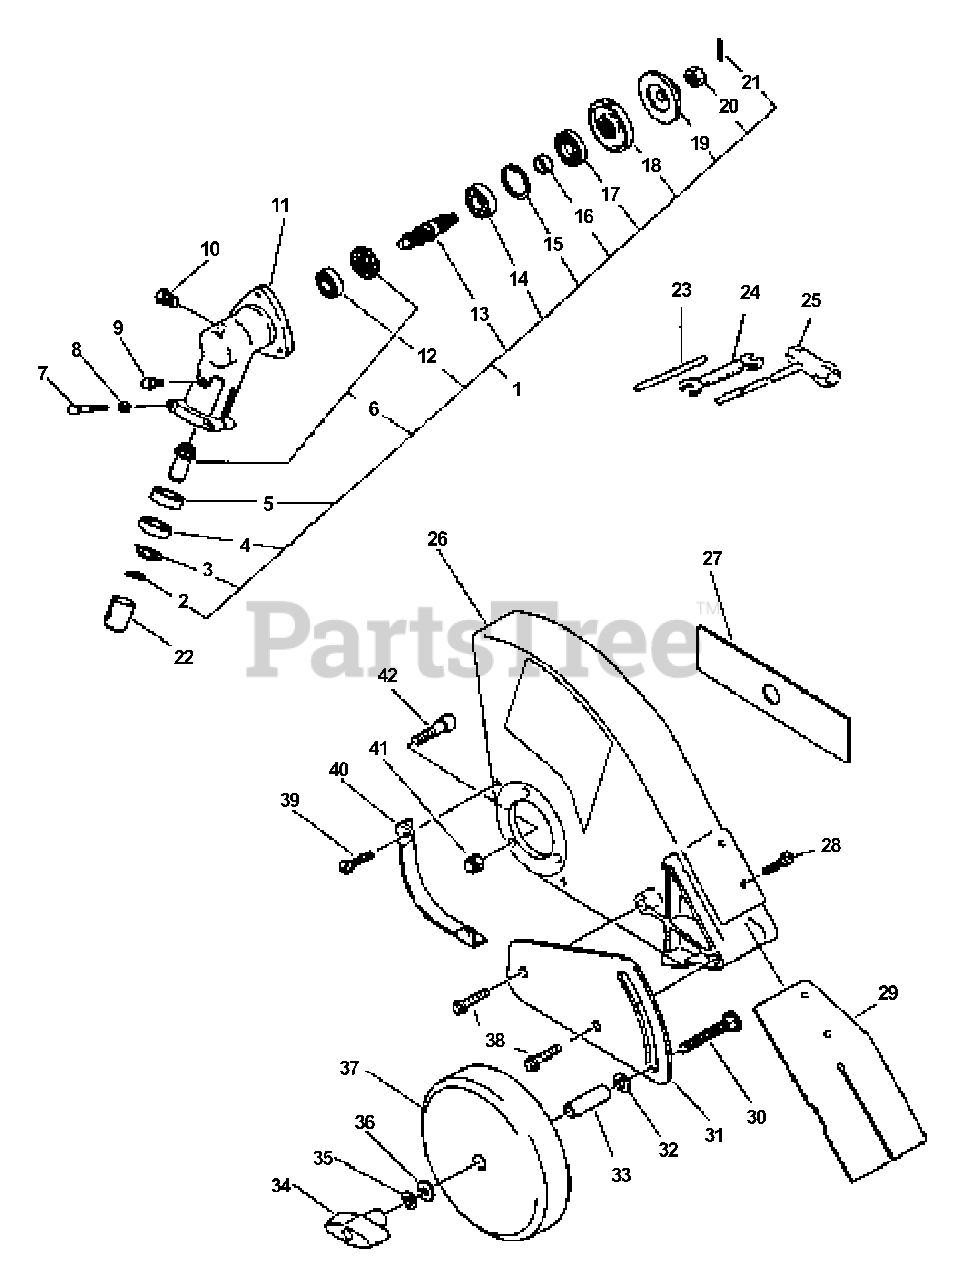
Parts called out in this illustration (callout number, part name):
1	GEAR CASE ASSY
2	RING, RETAINING - 12
3	RING, RETAINING - 22
4	BEARING, BALL - 6900Z
5	BEARING, BALL - 6900
6	GEAR SET - BEVEL
7	BOLT - 5X30
8	WASHER - 5
9	SCREW - 5X10
10	BOLT - 8X8
11	CASE, GEAR
12	BEARING, BALL - 609
13	GEAR - SHAFT
14	BEARING, BALL - 6201
15	RING, RETAINING - 32
17	SEAL, OIL
18	ADAPTOR, BLADE - UPPER
19	ADAPTOR, BLADE - LOWER
20	LOCKNUT - LEFT HAND
21	PIN, SPLIT - 2X22
22	COLLAR
23	LOCKING TOOL
24	SPANNER - 8X10mm
25	T-WRENCH - 17X19mm
26	SHIELD, DEBRIS
27	BLADE, EDGER
28	SCREW - 3
29	FLAP, DEBRIS
30	BOLT - CARRIAGE
31	BRACKET, WHEEL
32	WASHER - 10
33	COLLAR - 12
34	WINGNUT - 5/16-18
35	LOCKWASHER - 8
36	WASHER - 8
37	WHEEL - 6X1.5
38	BOLT - 8
39	SCREW - 4X16
41	LOCKNUT - 5
42	SCREW - 5X22
